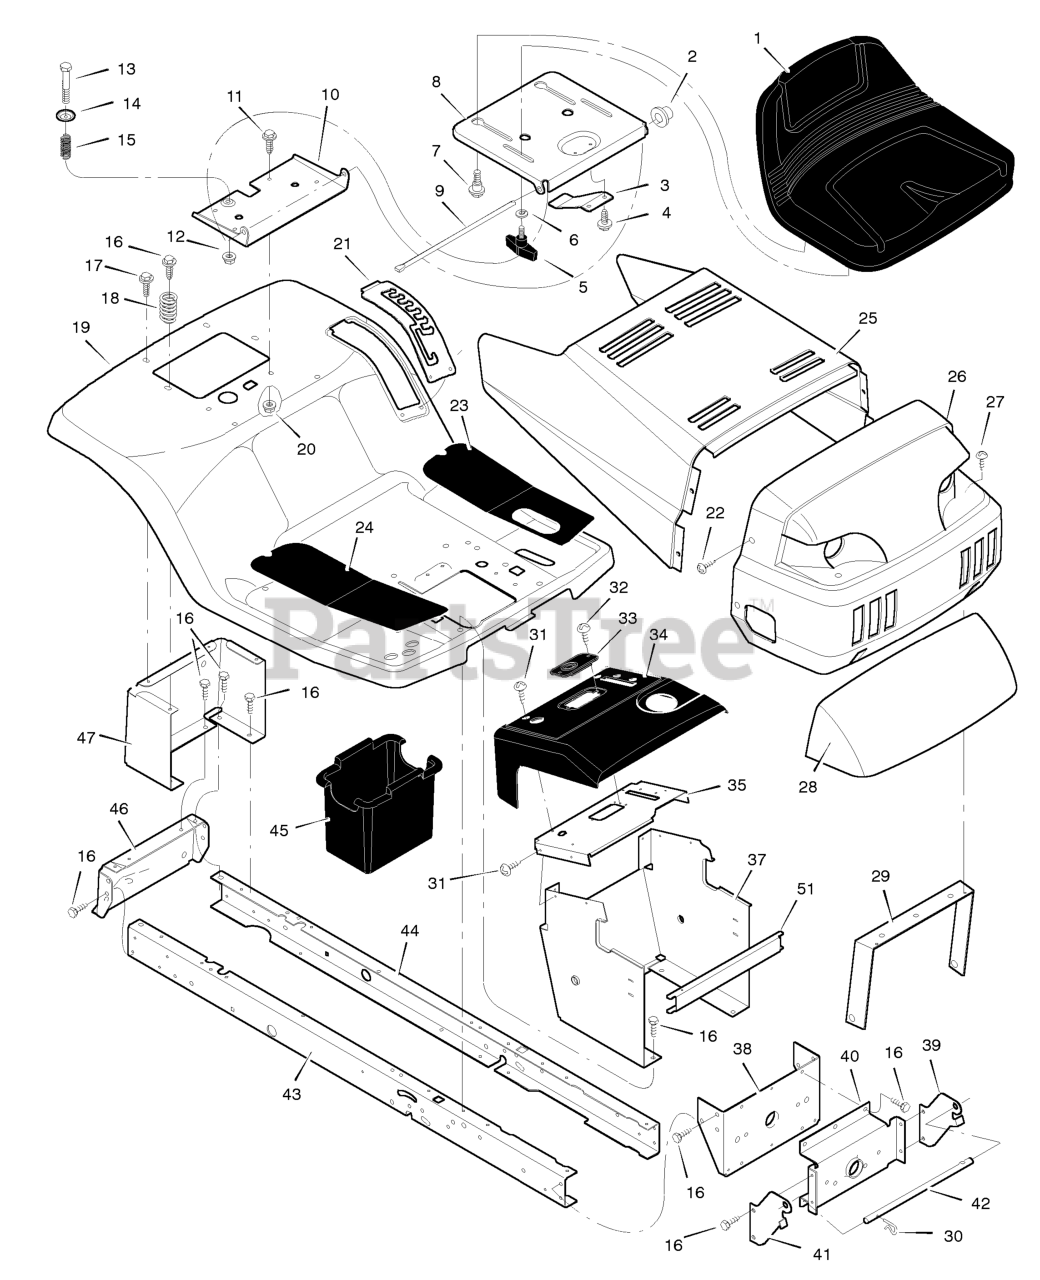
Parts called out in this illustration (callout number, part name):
2	Cap, Push On
5	Bolt, Wing
6	Washer
7	Bolt, Shoulder
8	Support, Seat
9	Rod, Pivot
10	Bracket, Pivot
11	Bolt
13	Bolt, Shoulder
15	Spring
19	Deck, Seat
20	Nut
21	Plate, Index
23	Mat, Left
24	Mat, Right
26	Grille Assembly
29	Brace, Grille
30	Pin, Hair
31	Screw
33	Bearing, Steering
35	Plate, Dash
36	Panel, Access
37	Support, Dash
38	Bracket, Rear Hanger
39	Support, Left Grille
40	Axle, Hanger
41	Support, Right Grille
42	Rod, Pivot
43	Frame, Right
44	Frame, Left
45	Container, Battery
46	Plate, Hitch
47	Panel, Rear
